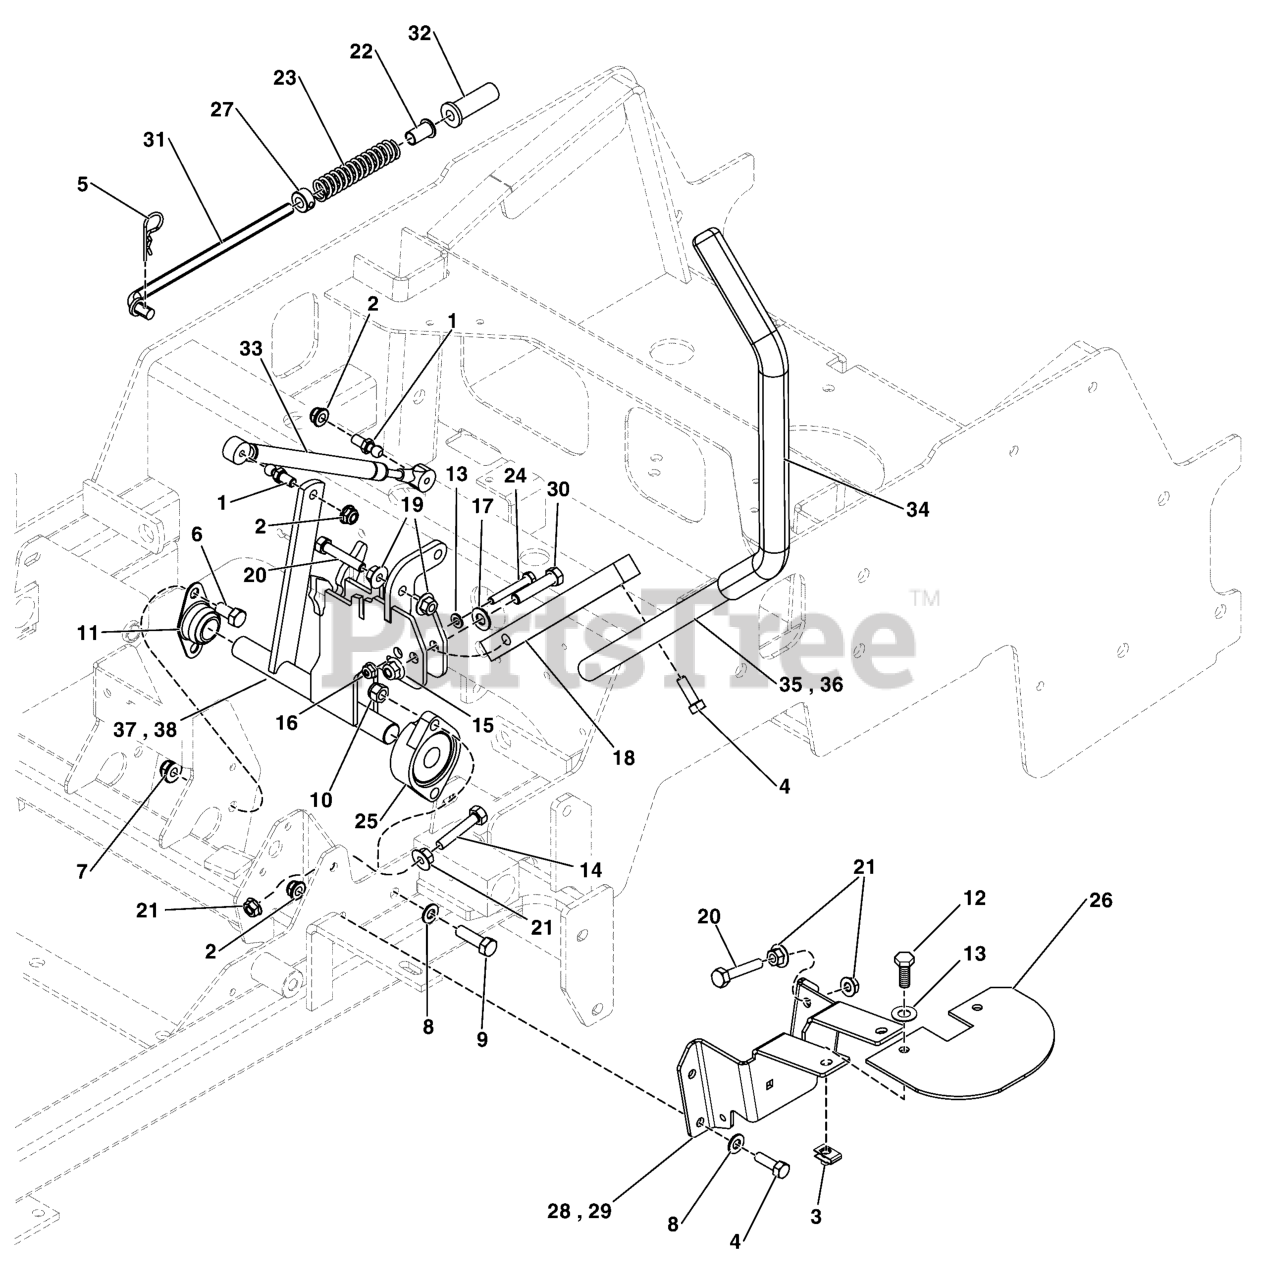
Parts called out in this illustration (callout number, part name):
1	10MM BALL STUD, 5/16-18 X 3/4 THDS
2	NUT, 5/16-18 HEX NYLOCK FLANGE NUT
3	BODY CLIP, 1/4-20 X 1/2" DEEP
4	SCREW, 5/16-18x0.750, GR5, WHIZ-LOCK, ZC
5	3/32 X 1-5/8 HAIR PIN CLIP
6	BOLT, 3/8-16 X 3/4" GD5 CZ
7	NUT, 3/8 - 16 HEX NYLOCK FLANGE
8	WASHER, 5/16" SAE
9	BOLT, Allen Head, 3/8-16 x 1-1/4
10	NUT, 3/8-16 HEX NYLON LOCK
11	BEARING, BRONZE FLANGE, 3/4"
12	BOLT, 1/4"-20 X 3/4" GD5 YZ
13	WASHER, 1/4 SAE
14	BOLT, 5/16-18 X 1-1/4 GD5 TFL, CZ
15	NUT, 3/8 - 16 HEX NYLOCK FLANGE
16	NUT, 1/4-20 Hex Nylock Flange
17	WASHER, 3/8 SAE
18	MOUNT, CONTROL ARM - BLK
19	NUT, 5/16-18 HEX SERRATED FLANGE (LARGE)
20	BOLT, 5/16-18 X 1-3/4 TFL, GD5 YZ
21	NUT, 5/16-18 HEX SERRATED FLANGE (SMALL)
22	BUSHING, FLANGE 3/8ID X 7/8 LONG
23	SPRING, REVERSE RETURN
24	BOLT, 1/4 X 20 X 1-3/4 GD5 YZ
25	BEARING, FLANGE
26	PLATE, NEUTRAL LOCK SHIELD - IS700 - BLK
27	COLLAR, 3/8" Set
28	PLATE, NEUTRAL LOCK, LH - BLK
30	BOLT, 3/8-16 X 1-3/4" GD5 CZ
31	ROD, NEUTRAL RETURN, CZ
32	FLANGED BUSHING, 3/8IDX.63ODX.8125FL
33	DAMPENER, CONTROL,#(P6709/P3610)
34	GRIP, FOAM, 1" ID, 16" LONG
35	WELD, HANDLE MOTION CNTRL, 19.0, 1.0, LH - BLK
37	WELD, CONTROL SHAFT, LOCKOUT, LH - BLK
